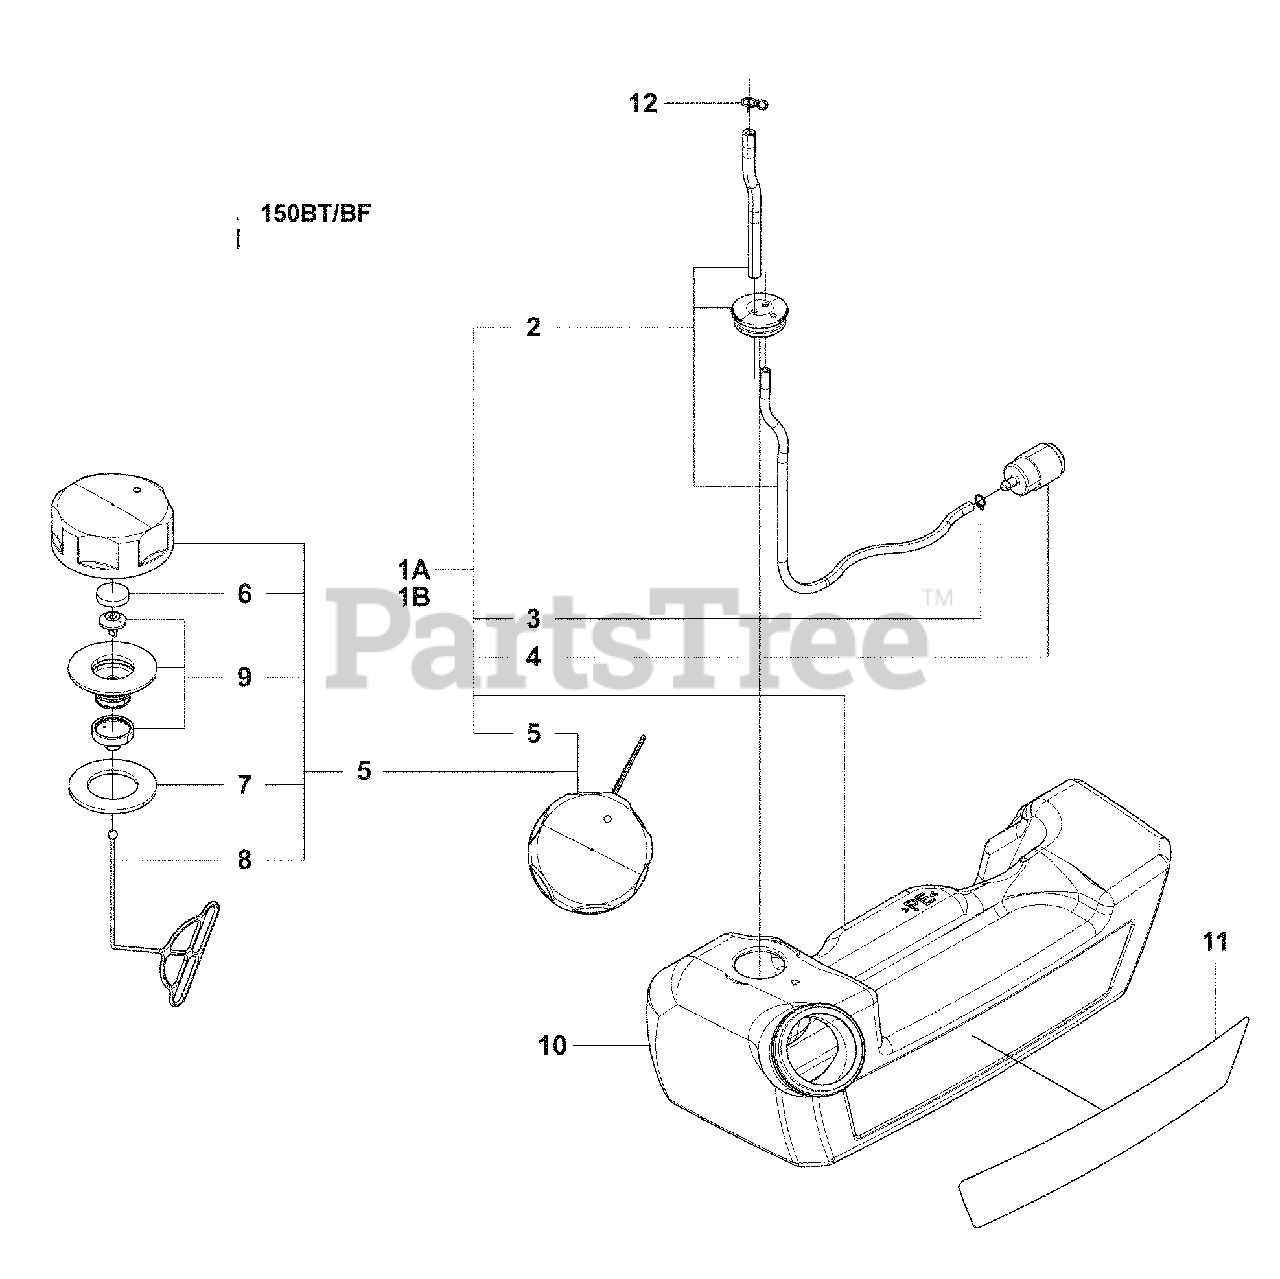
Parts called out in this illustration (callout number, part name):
1A	Tank Assembly
1B	Tank Assembly
2	Pipe, Complete
3	Clip
4	Fuel Filter Assembly
5	Fuel Cap Assembly
6	Air Filter
7	Packing
9	Holder, A
12	Clip
